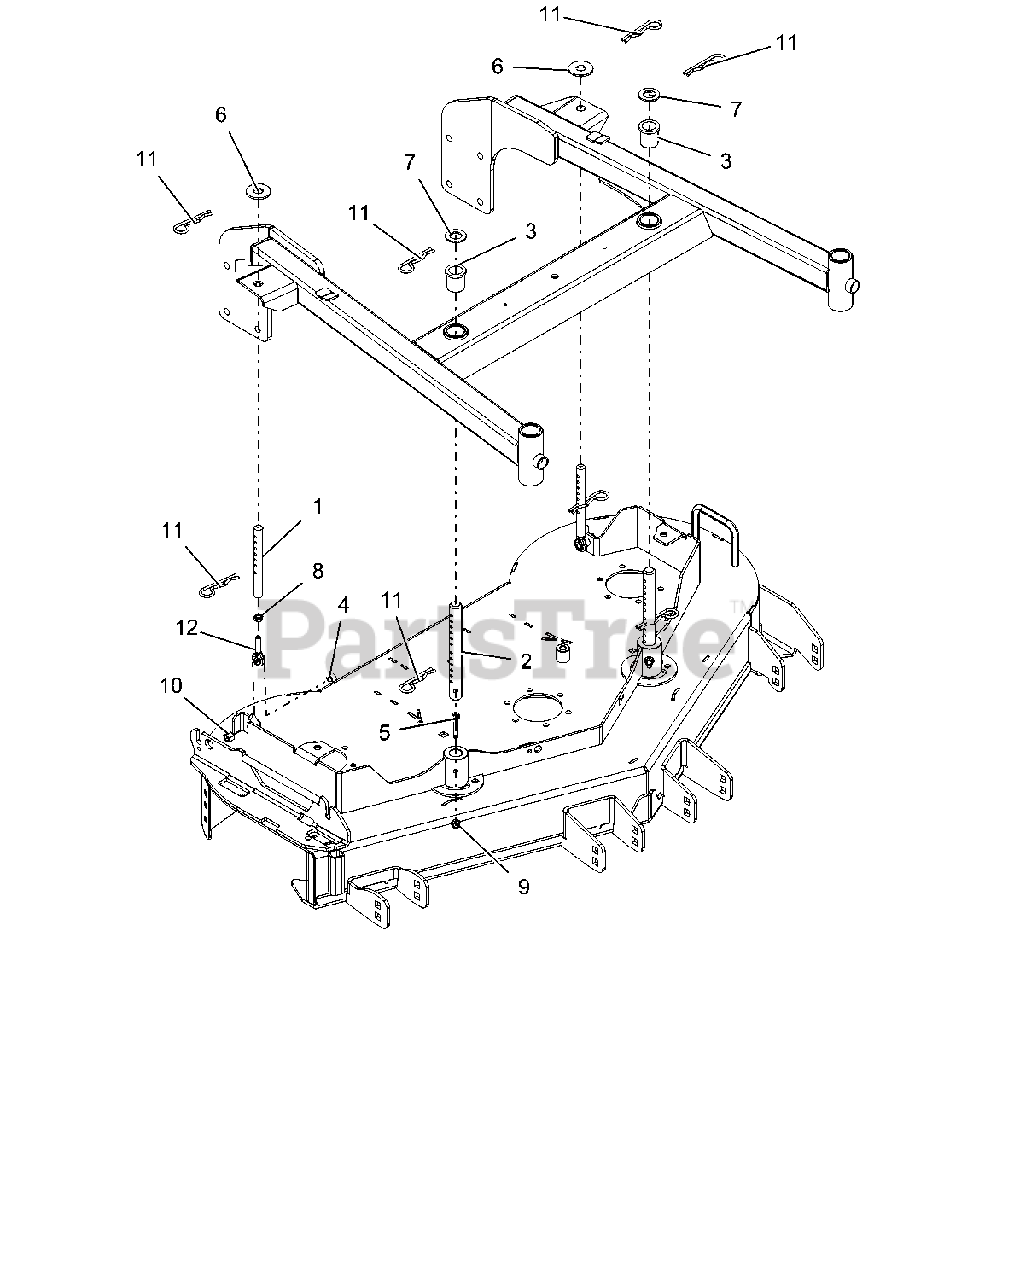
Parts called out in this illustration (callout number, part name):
1	ROD, REAR HOC
2	PIN, FRONT HOC
3	BSHG-FLG 1.00X1.25X1.5X1.5
4	BSHG, SLV REV
5	BLT-HEX .31-18X2.50 GR8 YWZC
6	WSHR-FL-STL.688X1.75X.134 YWZ
7	WSHR-FL-STL .875X1.500X.1196YZ
8	NUT-JAM .375-24 YWZC
9	@NUT-SPNLK-FLG .312-18 YWZC
10	NUT-LK-NYL .38-16 YWZC
11	PIN-HAIR-INT .17X.68X3.50 YWZC
12	ROD, END 3/8 RH REV
